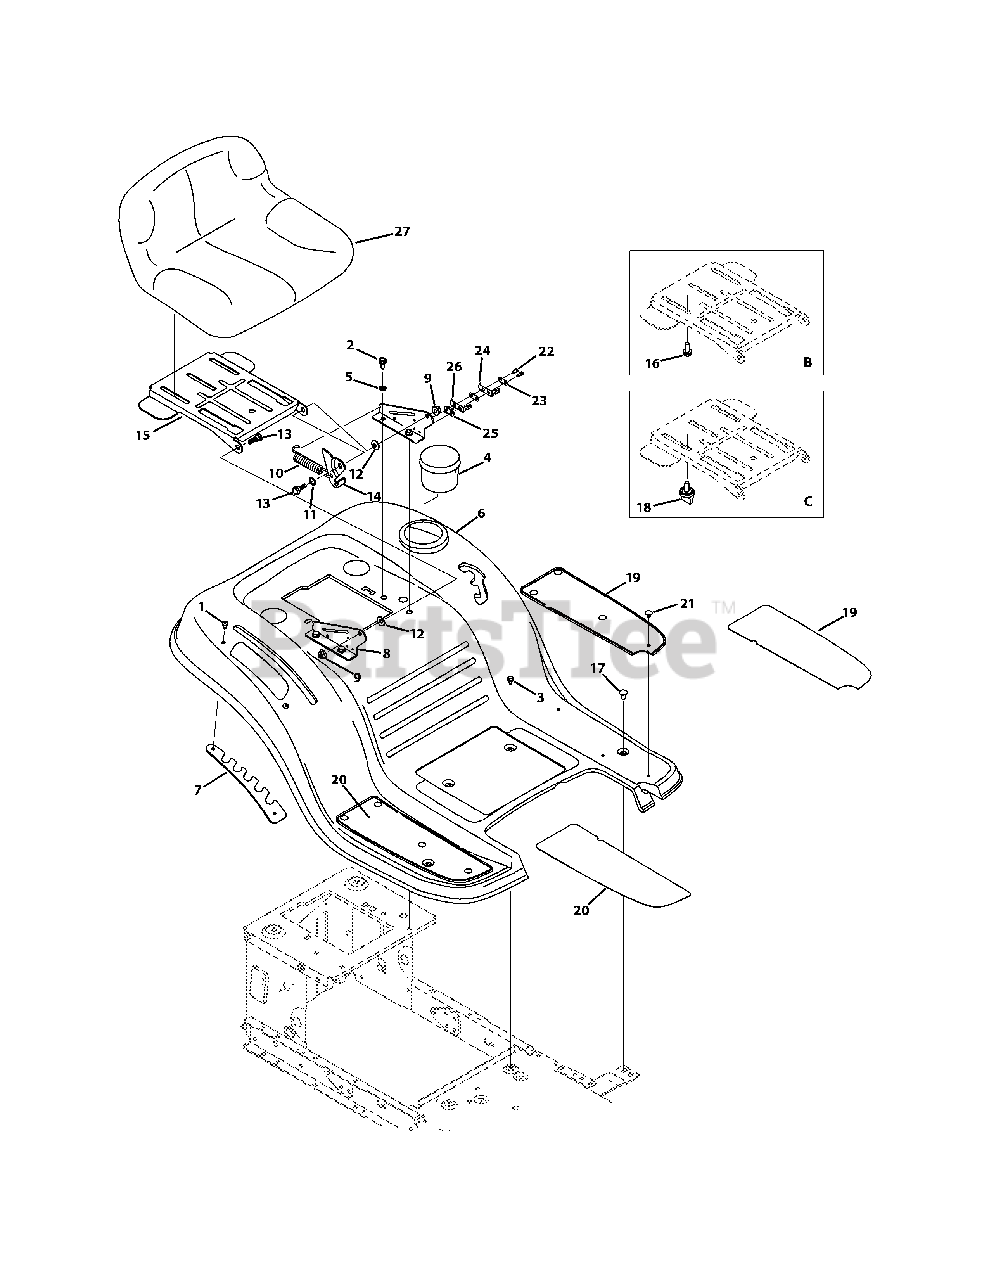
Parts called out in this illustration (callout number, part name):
1	Screw, 1/4-20 x .500
2	Screw, 5/16-18 x .750
3	Screw Pan Torx Head, 1/4-20 x .500
4	Cup Holder
5	Loack Washer, 5/16
6	Fender - Red
6	Fender - Black
6	Fender - Green
7	Lift Adjuster Bracket - Powder Black
8	Seat Mount Bracket - Powder Black
9	Flangelock Nut, 5/16-18
10	Extension Spring
11	Flat Washer, .510x .750 x .033
12	Bell Washer, .340 x .872 x .060
13	Shoulder Screw, 5/16-18 x .437 x .268
14	Lift Seat Bracket
15	Pivot Seat Manual Adjust Bracket
16	Hex Head Flange, 3/8-16 x .875
17	Screw Carriage, 1/4-20 x .62
18	Knob, 3/8-16 x .875
19	Foot Pad, LH
19	Foot Pad, Abrasive, LH
20	Foot Pad, RH
20	Foot Pad, Abrasive, RH
21	Ratchet Clip, .250 x .500
22	Screw, 8-18 x .500
23	Insulator Plate
24	Outer Seat SPring
25	Insulator Boss Plate
26	Inner Seat Spring
27	Medium Back Seat, Black, Set-up B
27	Low Back Seat, Black, Set-up B or C
